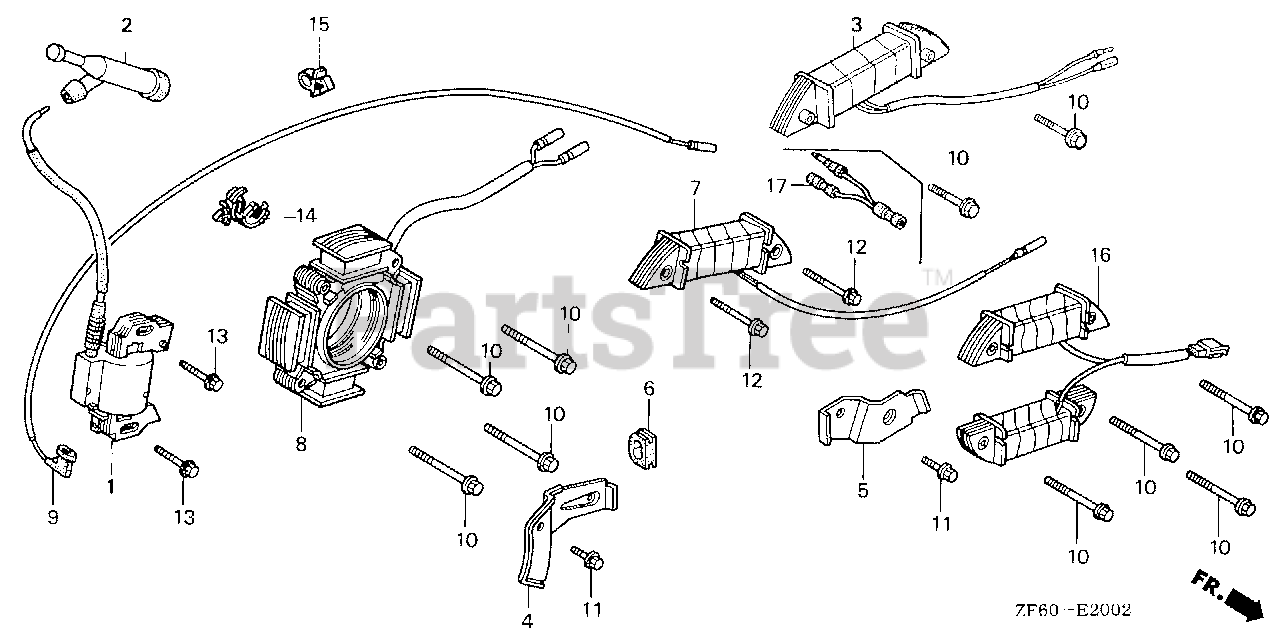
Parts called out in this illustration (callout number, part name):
1	COIL ASSY., IGNITION
2	CAP ASSY., NOISE SUPPRESSOR (NICHIWA Y-EZ RTFM256)
6	GROMMET, WIRE
9	WIRE, STOP SWITCH (430MM)
13	BOLT, FLANGE (6X28) (CT200)
